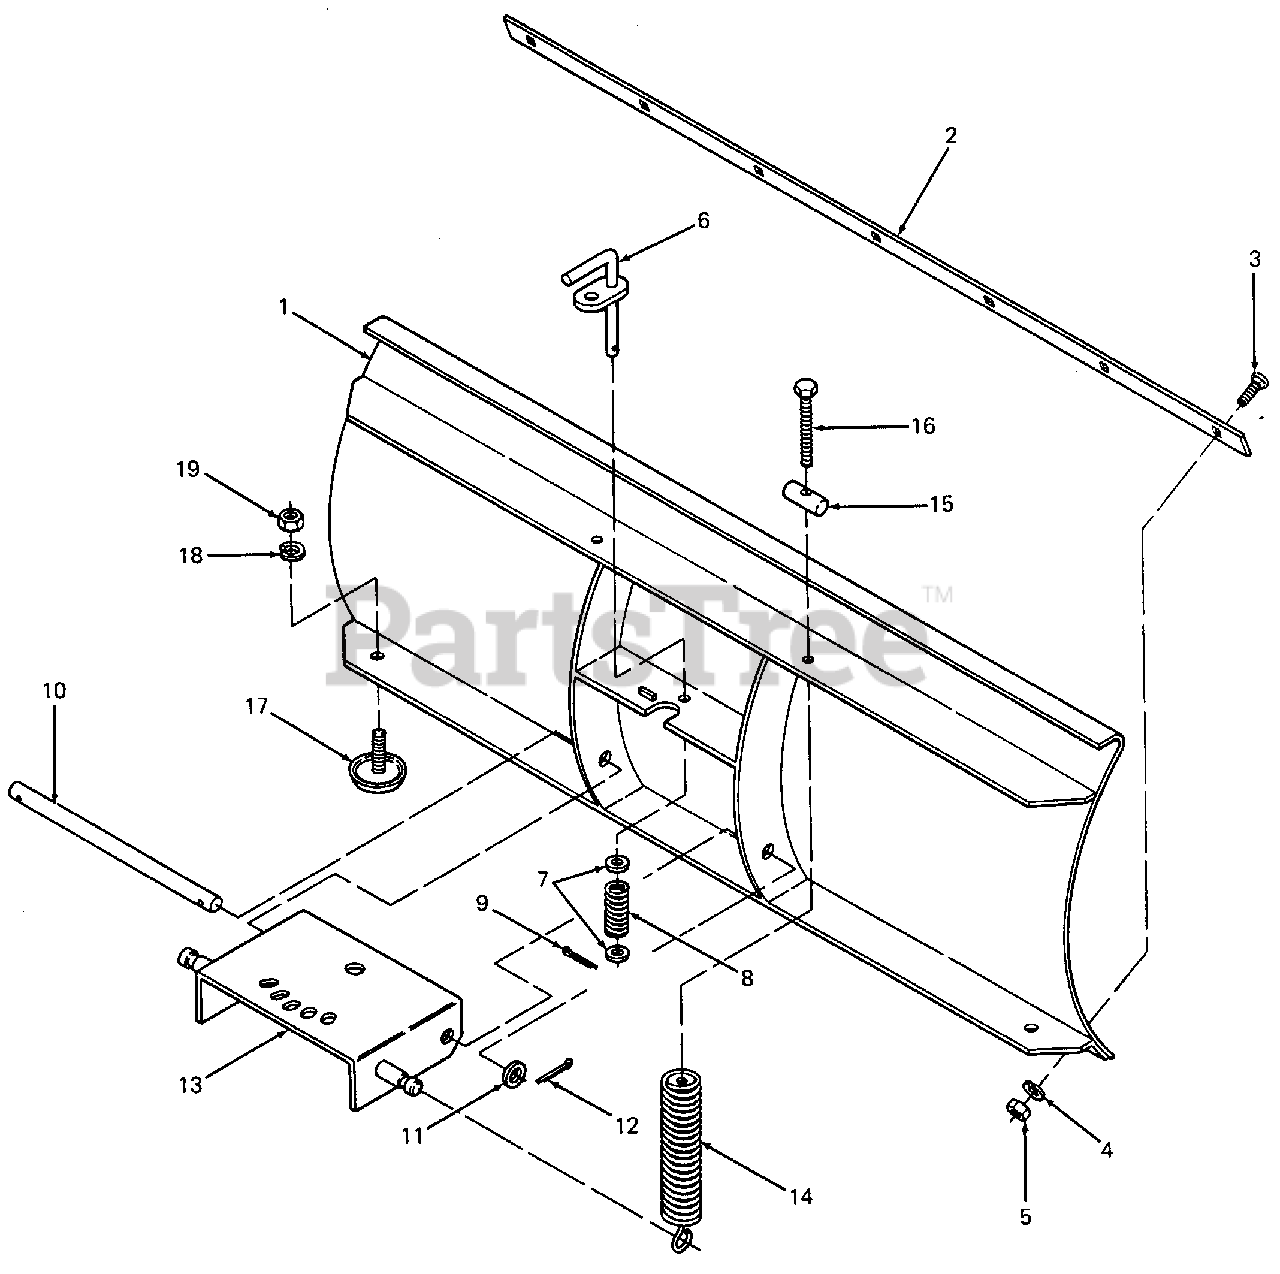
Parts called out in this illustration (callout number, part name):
1	Snowblade - 42 inch
3	Bolt, Sq Neck Carriage, 5/16-18 X 7/8 Lg
4	Washer, Lock, 5/16
5	Nut, Hex, 5/16-18 GR5
6	Lock, Spring Trip
7	Washer, Flat, .406 X .75 X .063 Thk
8	Spring, Compression
9	Pin, Cotter, 7/64 Dia X 7/8 Lg
10	Rod, Blade Pivot
11	Washer, Flat, .64 X 1.25 X .100 Thk
12	Pin, Cotter, 5/32 Dia X 1.25 Lg
15	Roller, Spring
16	Screw, Hex Cap, 3/8-16 X 3.5 Lg GR5
18	Washer, Lock, 1/2
19	Nut, Hex Jam, 1/2-13 GR5
